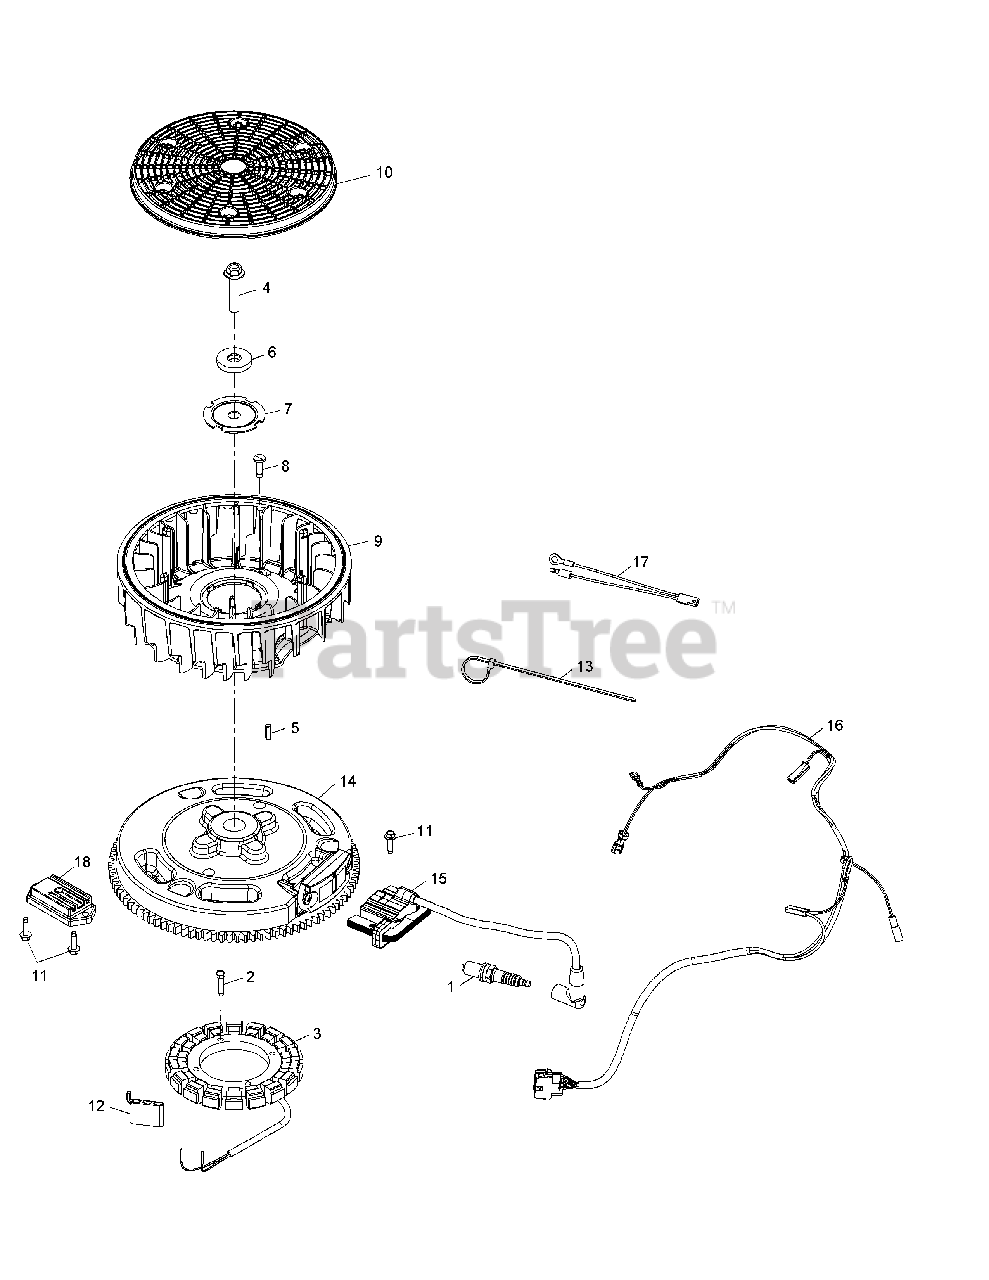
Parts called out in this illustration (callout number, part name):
2	Thread Forming Screw
3	15 Amp Stator Kit
4	Hex Flange Screw
7	Fan Mounting Plate
8	Flywheel Fan Retainer
11	Thread Forming Screw
14	Flywheel Assembly
15	Ignition Module
16	Wiring Harness
18	Rectifier Regulator
